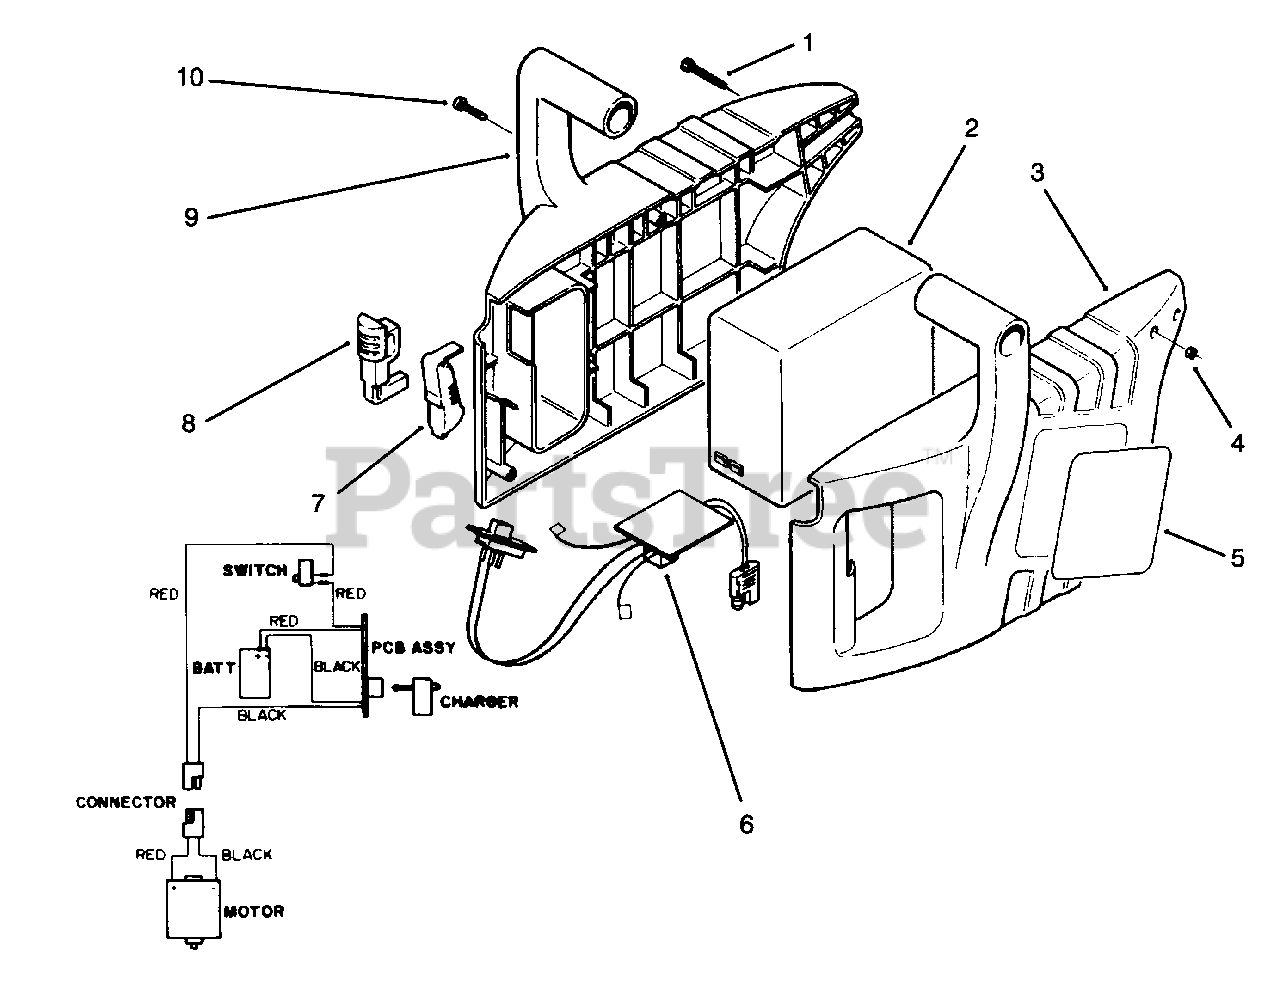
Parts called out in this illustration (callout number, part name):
1	Screw-Self Tapping
3	Handle & Battery Case R.H.
5	Decal-Toro
6	Wiring Harness
8	Lock-Trigger
9	Handle & Battery Case L.H.
10	Screw
